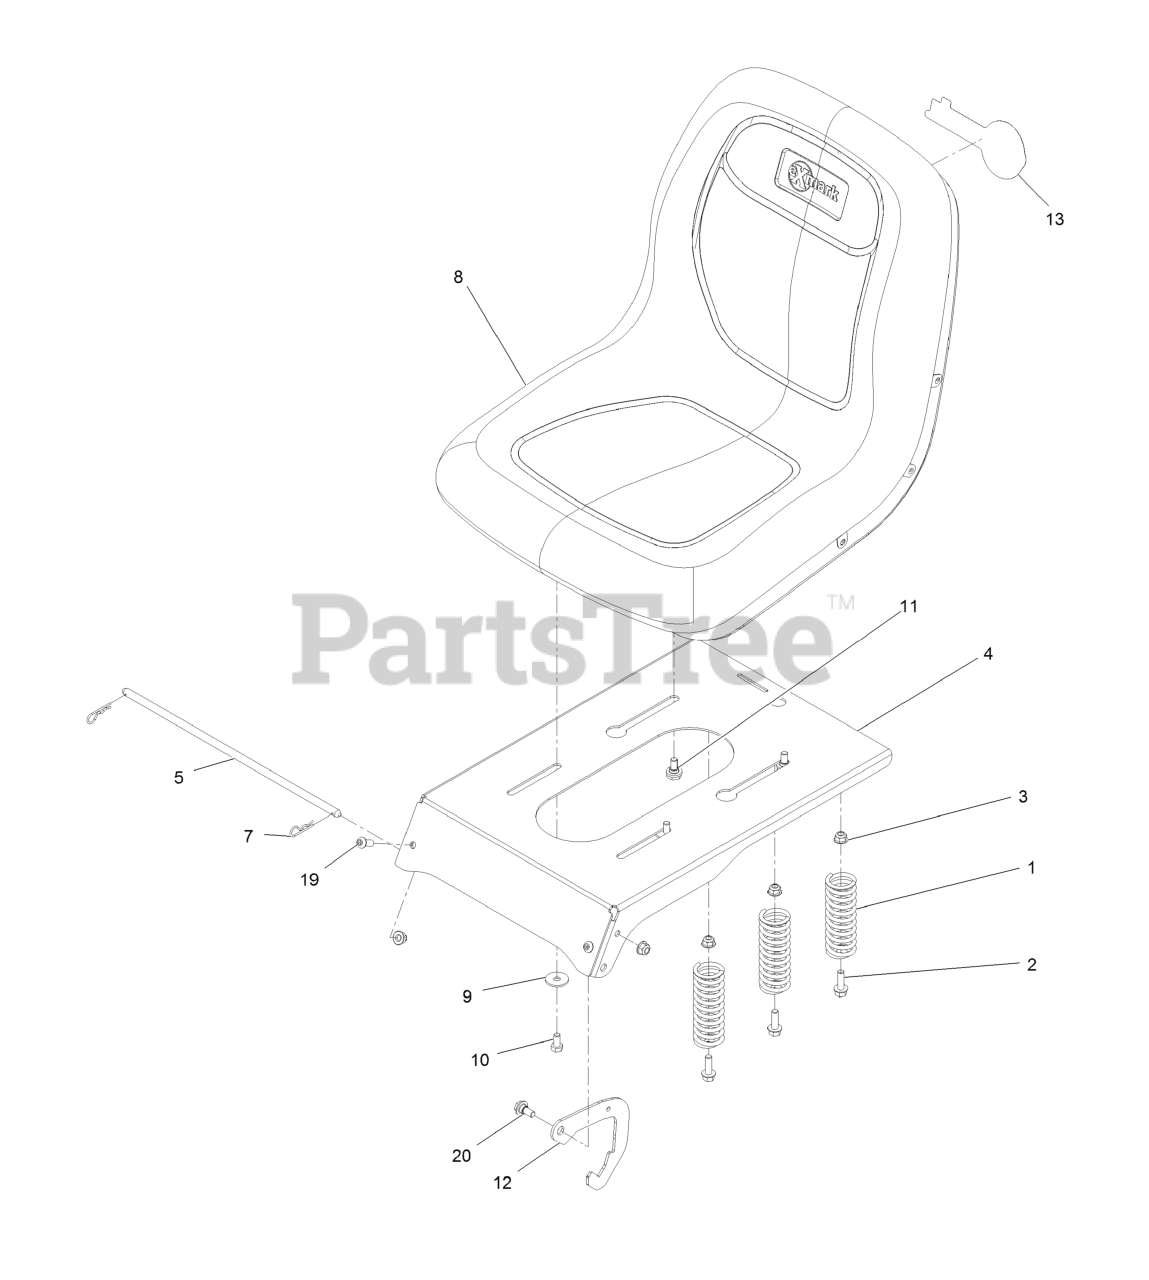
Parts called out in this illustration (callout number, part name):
1	SPRING-COMPRESSION
2	SCREW-HHF
3	NUT-HF, NI
5	Rod-Pivot, Narrow
7	PIN-COTTER
8	SEAT-18 IN
9	WASHER-PIVOT
10	SCREW-HH
11	BOLT-SHOULDER,HFH
12	Seat Latch
13	DECAL-EXMARK LOGO
19	SCREW-HSBH
20	SCREW-SHOULDER
